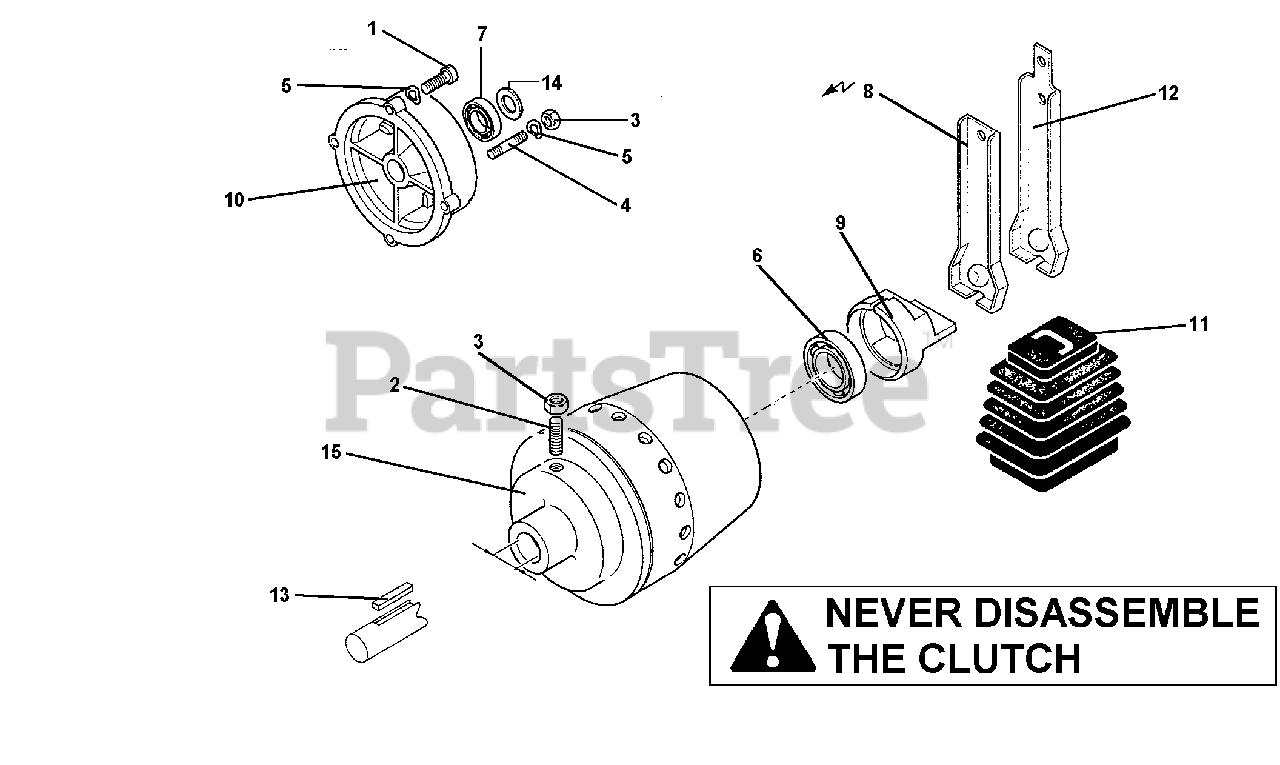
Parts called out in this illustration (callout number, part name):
1	SCREW 5/16X7/8"
2	SCREW M8X30
4	STUD,M8X40X14X14"
5	WASHER, WAVE"
6	BEARING,M17X40X12"
7	BEARING,20X47X14"
8	CLUTCH LEVER, ELECTRIC START"
9	CONE PUSHER
10	FLANGE, 5HP B&S"
12	LEVER, RECOIL START"
14	WASHER, 5HP"
15	CLUTCH, 5HP B&S .75"" SHAFT"
